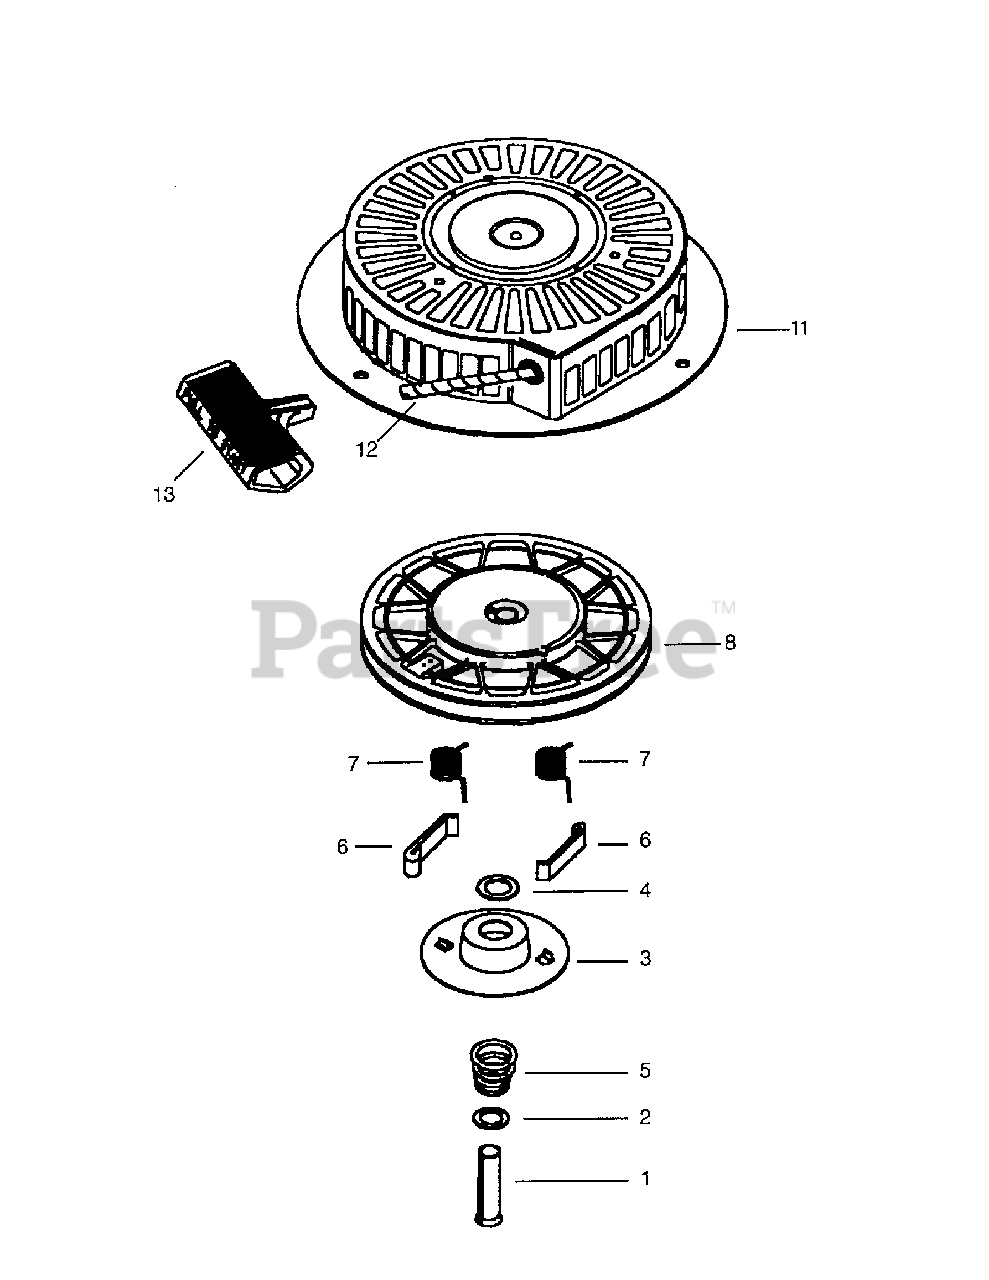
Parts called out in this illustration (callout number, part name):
5	Brake Spring
6	Starter Dog
7	Dog Spring
8	Pulley & Rewind Spring Assy.
11	Starter Housing Assy.
12	Starter Rope
13	Mitten Grip Handle
